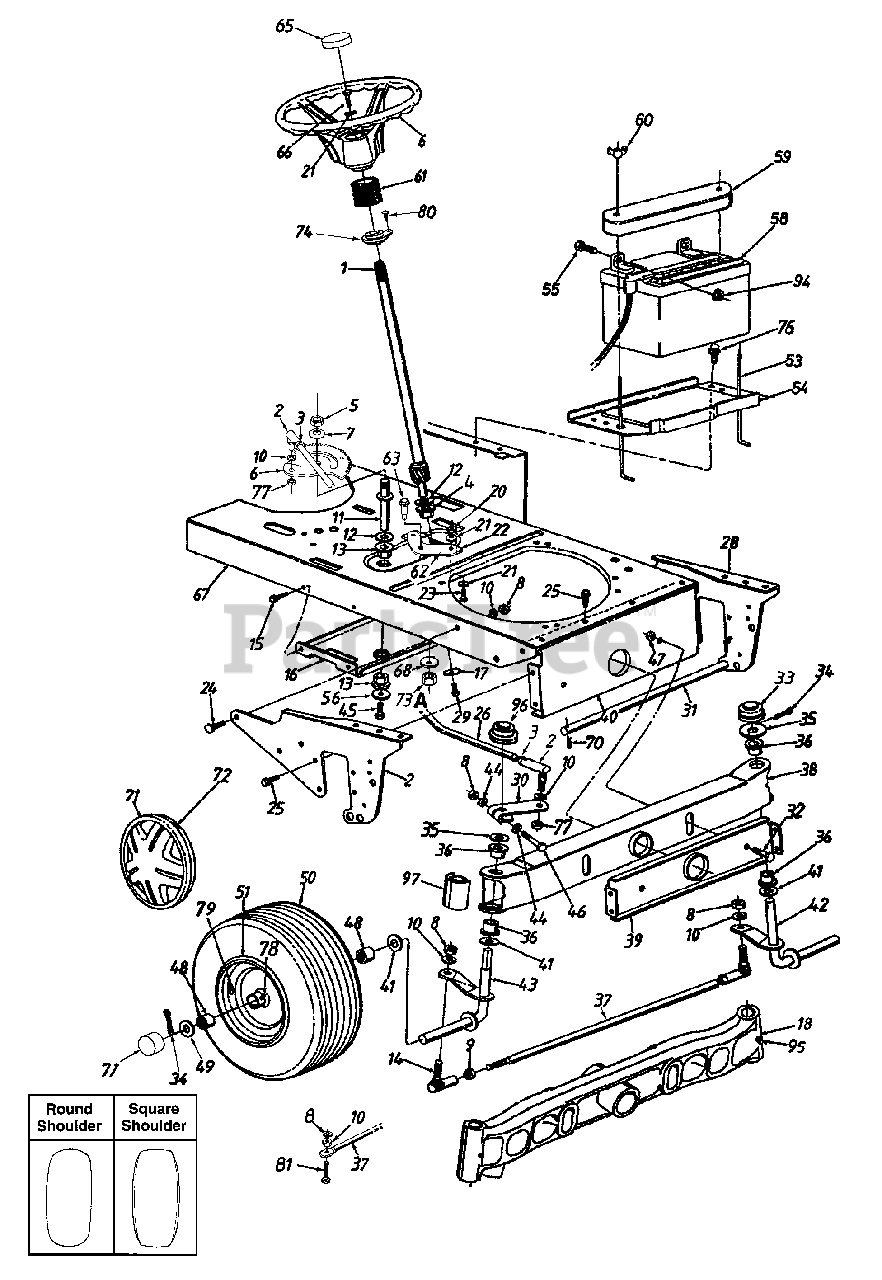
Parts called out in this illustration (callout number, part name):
1	Steering Shaft Ass'y.
2	Ball Joint 7/16-20 Thd.
3	Hex Jam Nut 7/16-20 Thd.
4	Hex Flange Brg.
5	Hex Jam Nut 5/8-18 Thd.
6	Steering Gear Segment
7	Bell-Wash. 5/8" I.D. x 1.25"
8	Hex Nut 3/8-24 Thd.
9	Hex Jam Nut 3/8-24 Thd.
10	L-Wash. 3/8" I.D.
11	Steering Gear Segment Shaft
12	Fl-Wash. .64" I.D. x 1.24" O.D.
13	Hex Flange Brg. .63" I.D.
14	Ball Joint Ass'y.
15	Hx Wash. Hd. TT-Tap Scr.
17	Cap
18	Pivot Bar Ass'y.
20	Hex Nut 5/16-24 Thd.
21	Bell-Wash. .345" I.D. x .88"
24	Ribbed Neck Bolt 3/8-24 x .8"
25	Hex Wash. TT-Tap Scr.
26	Steering Drag Link
31	Deck Connecting Rod
32	Shld. Bolt .498" Dia. x 2.45"
33	Cap
34	Cotter Pin 5/32" Dia.
35	Flat Washer
36	Flange Brg. .757" I.D.
37	Tie Rod
41	Fl-Wash. .76" I.D. x 1.49" O.D.
42	Front Axle Ass'y.-L.H.
43	Front Axle Ass'y.-R.H.
44	Flat Washer
45	Hex L-Scr. 5/16-18 x .62" Lg.
46	Hex Bolt 3/8-24 x 2.50" Lg.
47	Hex L-Nut 3/8-16 Thd.
48	Flange Brg. .75" I.D.
49	Fl-Wash. .71" I.D. x 1.5" O.D.
50	Wheel Ass'y. Comp.
51	Rim Only
56	Fl-Wash. .33" I.D. x 1.25" O.D.
58	Battery
59	Battery Cover
60	Wing Nut Plastic 1/4-20 Thd.
61	Steering Bellow
65	Steering Cap
66	Hex L-Bolt 5/16-18 x 1" Lg.
70	Internal Cotter Pin
71	Hub Cap
72	Spring Clip
73	Hex Nut 3/8-16 Thd.
74	Flange Bearing (Style A)
76	Hex Wash. B-Tap Scr. 1/4 x .62"
77	Hex Jam L-Nut 3/8-24 Thd.
78	Grease Fitting
79	Air Valve
80	C.-Sunk Scr. #10 x 5/8"
81	Hex Bolt 3/8-24 x 1.5"
94	Hex L-Nut 1/4-20 Thd.
95	Grease Fitting
